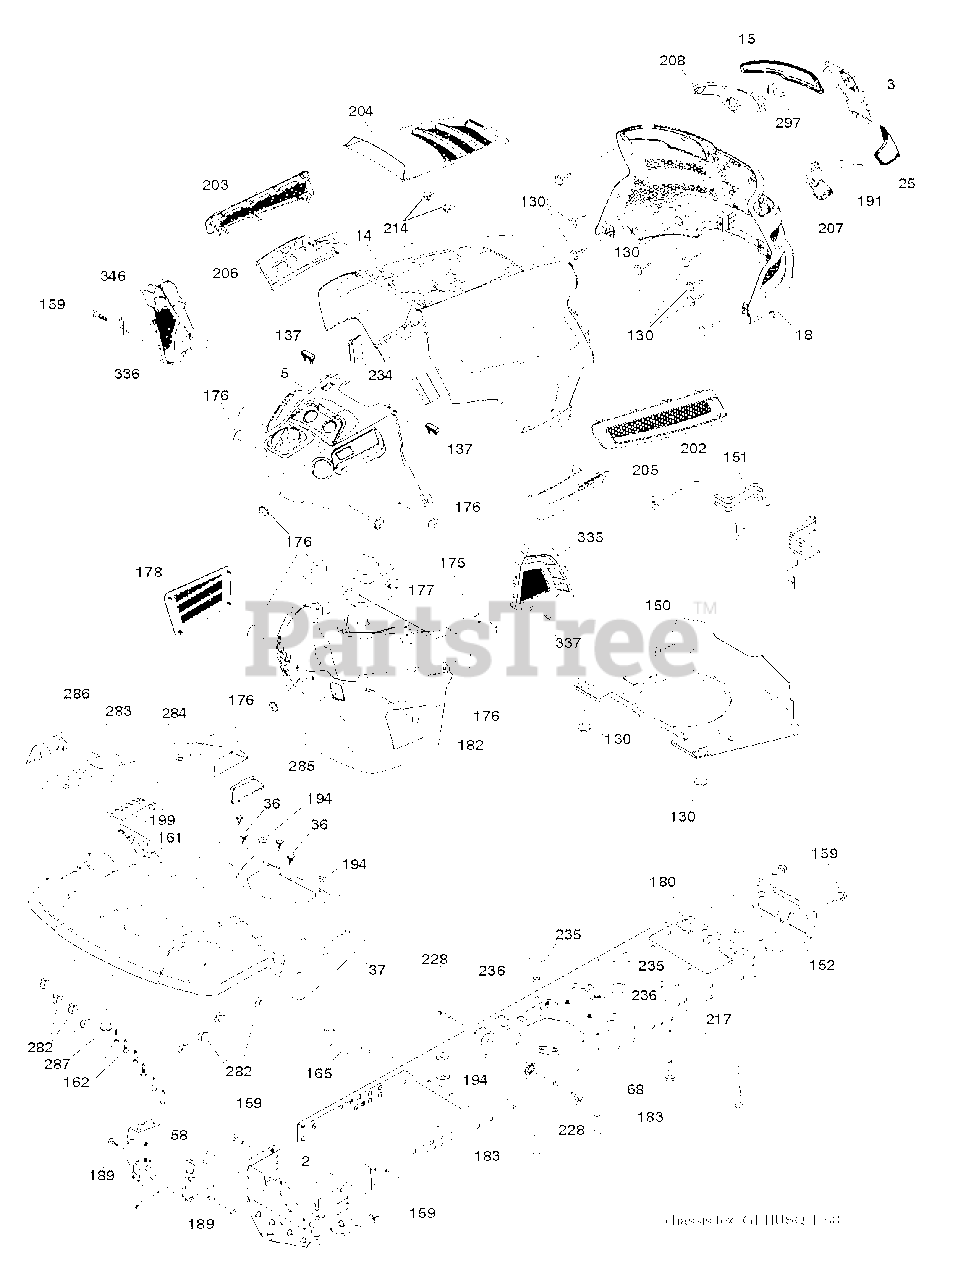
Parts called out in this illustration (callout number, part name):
2	DRAWBAR.1PC.NSTL
3	APPLIQUE.SUBASM.GT.HUSQ.II
5	DASH.UPPER.ASSY.GT2.DUAL
14	HOOD.ASM.HUSQVARNA.GT.TEX.422
15	LENS.HEADLIGHT.LH.GTII.2011
18	GRILLE.SUBASM.GT.HUSQ.II
25	LENS.HEADLIGHT.RH.GTII.2011
36	SCREW 5/16"
37	FENDER.TLT.FS.W/CPH/FW/RSF.ORN
58	DRAWBAR UPPER 2PC SMALL FENDER
68	SCREW LT
130	SCREW.#10 X 0.750.BOS
137	BUMPER DASH
150	AIR.DUCT.GTV.BLACK
151	BRACKET.PIVOT.HOOD.GT.HUSQ.II
152	SHIELD.BROWNING.PNT.GT.V2
159	SCREW, 3/8-16X3/4
161	WINDOW.FUEL.LT.HUSQ.TEX.498
162	SCREW.HI-LO.CONSOLE
165	SUPPORT.TANK.REAR.B/TE
175	PLATE.CROSSMEMBER.HUSQ
176	SCREW.#10-24X5/8.RN.QU
177	BUSHING, STEERING
178	CARGO.ASM.NET.TXGT.W/C
180	CHASSIS.STAMPING.LT/GT
182	DASH.LOWER.COMMON.12V.ADAPTOR
183	BOLT.5/16-18X1-1/4 FULL THD
189	SCREW
191	INSERT.REFLECTIVE.RH.HUSQ.GTII
194	NUT LOCK HEX FLANGE 5/16-18
199	PLATE.DECK.LIFT.HUSQ.LT
202	VENT.SIDE.RH.GT.HUSQ.II.
203	VENT.SIDE.LH.GT.HUSQ.II.498
204	VENT.TOP.HUSQ.GT2
205	SIDE.TRIM.RH.GT.HUSQ.II
206	SIDE.TRIM.LH.GT.HUSQ.II.GRAY
207	BEZEL LIGHT.RH.GT.II.MYLAR
208	BEZEL LIGHT.LH.GT.II.MYLAR
214	CLIP.RETAINER.TINNER.
217	ROD.PIVOT.HOOD
228	STUD.FASTNER.W/ANTI-ROTATE
234	BUMPER.HOOD.TEX.HUSQVARNA
235	SPACER FENDER
236	NUT.CENTERLOCK.5/16-
282	CLIP.RETAINER.CONSOLE.LT.HUSQ
283	CONSOLE.DECK.LIFT.R.SDFL.HUSQ
284	CONCOLE.CNTRL.PDL.HUSQ.LT.498
285	CONSOLE INSERT RH
286	CONSOLE.INSRT.LH.HUSQ.LT.BLACK
287	SCREW 1/4X20
297	INSERT.REFLECTIVE.LH.HUSQ.GTII
335	COVER.RH.CLOSE.OUT.BLACK
336	COVER-LH.LOWER.DASH.GT2.BLACK
337	CLIP.XMAS.TREE.ITW.2622-00
346	CLIP,INSULATOR
